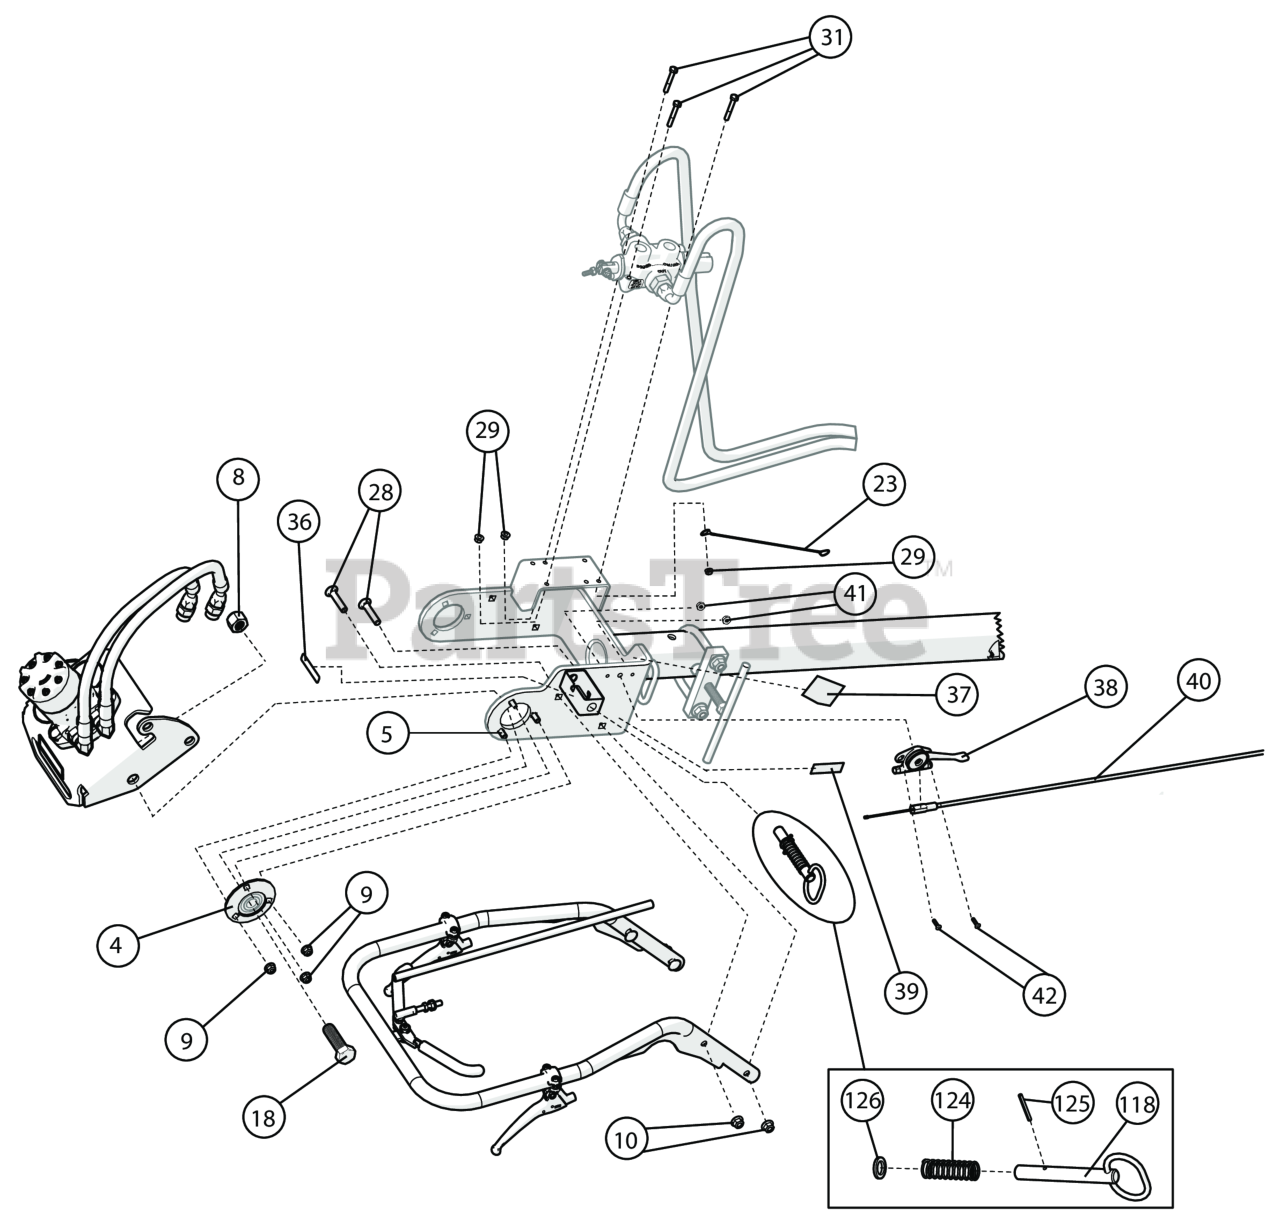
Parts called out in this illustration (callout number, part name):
4	BEARING AND FLANGETTE ASSY .75"
5	BOLT CARRIAGE 5/16"-18 X 1" ZP
8	NUT LOCK 3/4" - 10 ZP
9	NUT-HEX-NYLK, FLG .3125-18 ZP
10	NUT-HEX-NYLK, FLG .375"-16 ZP
18	SCREWCAP 3/4-10 X 2 1/2" LG Z/P GR 5
23	LANYARD, 12" COATED STEEL
28	BOLT CARRIAGE 3/8"-16 X 2" ZP
29	NUT-HEX-NYLK, FLG .250"-20 ZP
31	SCREWCAP 1/4"-20X1 3/4" HCS ZP
36	LABEL, LOCK SLIDE UNLOCK
37	DECAL, ENTANGLEMENT HAZARD
38	CONTROL THROTTLE BLOWER
39	LABEL THROTTLE BC
40	CABLE THROTTLE CONTROL 70"
41	NUT LOCK LT #10-24 HEX
42	SCR-MAC, FCSNKHD, 10-24X.750" T1ZP
118	PIN, WELD ON SPRING LATCH
124	SPRING, WELD ON SPRING LATCH
125	PIN, SPRING, WELD ON SPRING LATCH
126	WSHR, STL, 5/8" ID
